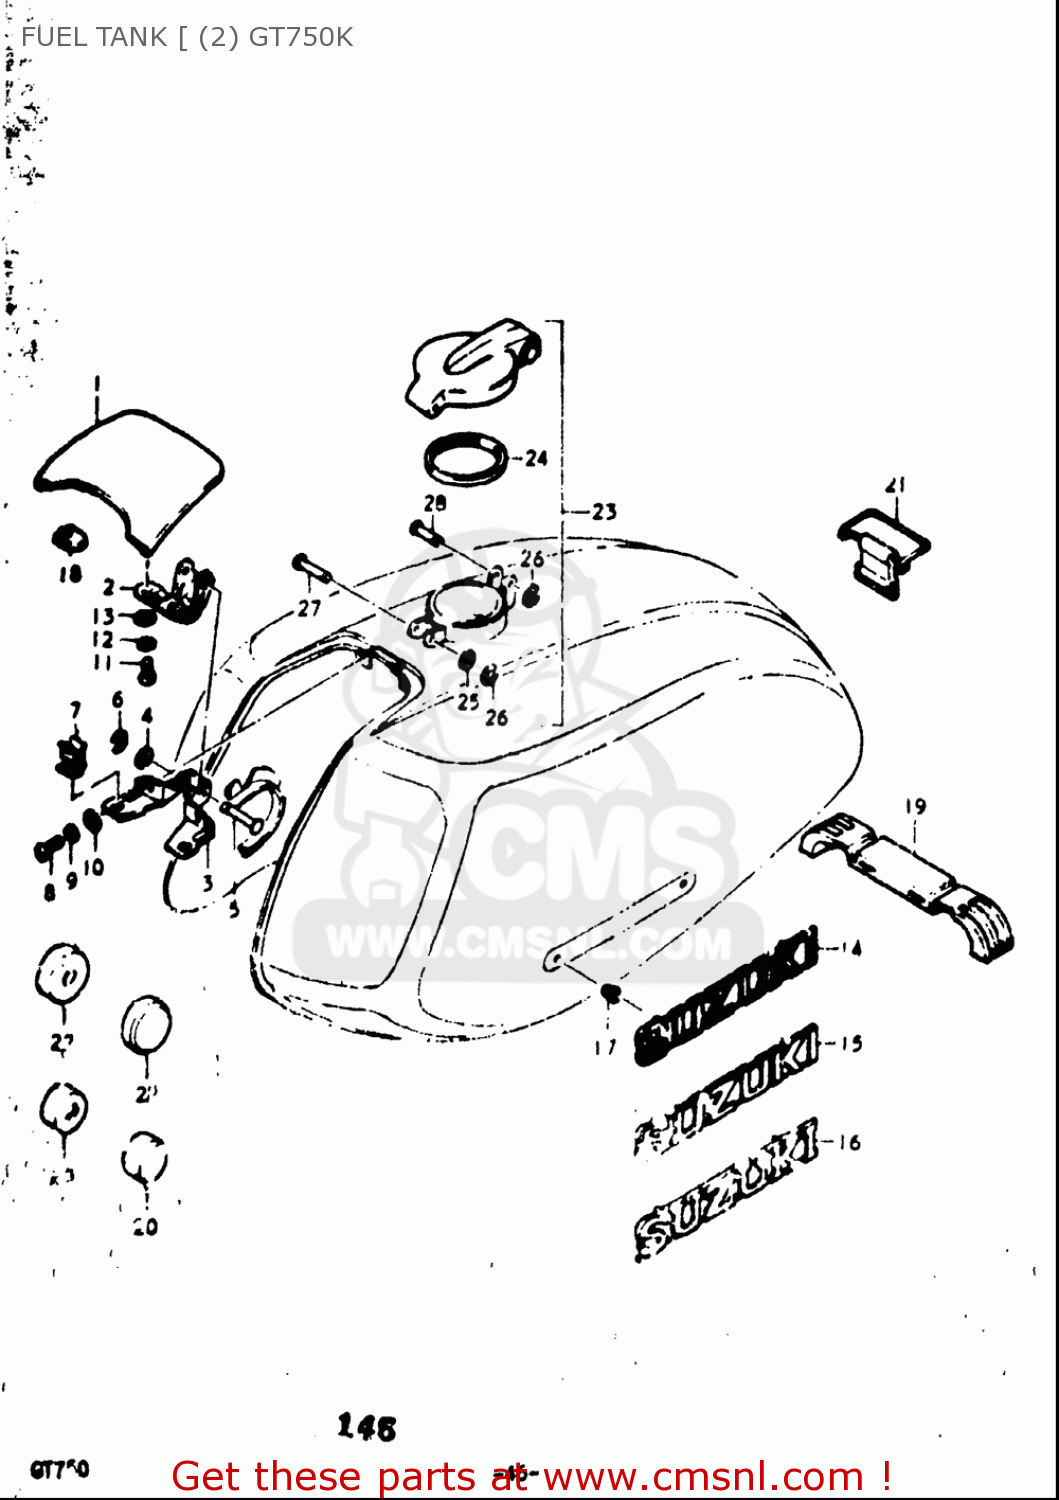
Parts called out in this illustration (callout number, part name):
4	WASHER
6	E RING
8	SCREW
9	WASHER,LOCK
10	WASHER
11	SCREW
12	WASHER,LOCK
13	WASHER
17	NUT
19	CUSHION
20	CUSHION
21	BAND
22	CUSHION
23	CAP ASSY,FUEL TANK
24	GASKET (NAS)
25	WASHER
26	E RING
